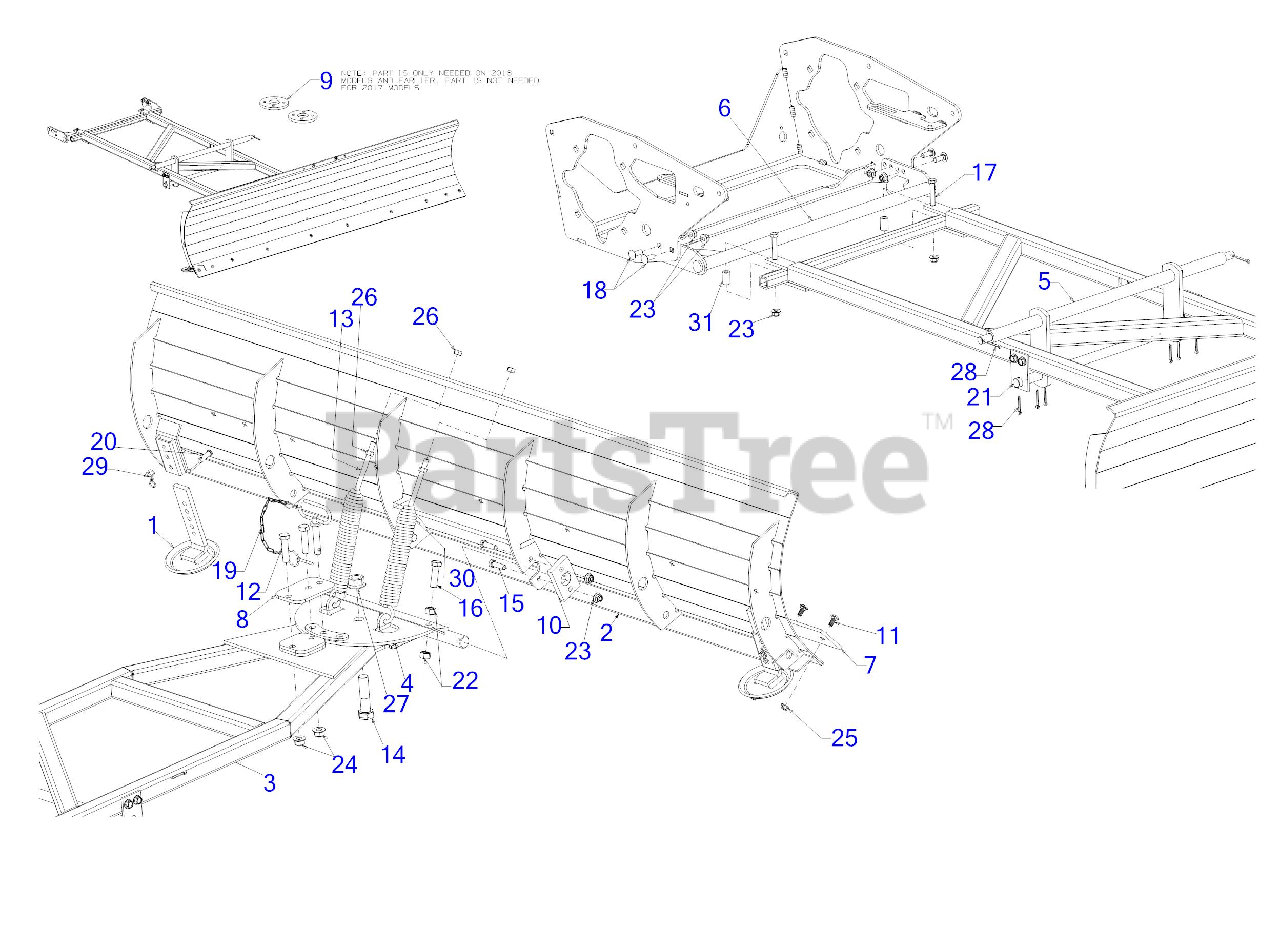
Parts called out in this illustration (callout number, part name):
2	72" SNOW BLADE WELDMENT
3	SNOW BLADE FRAME
4	BLADE PIVOT BRACKET
5	LIFT ROD WELDMENT
7	72" SCRAPER BLADE
10	PIVOT ROD PLATE
11	CARRIAGE BOLT 5/16-18 x .75
12	SCREW 1/2-13 x 2 GR5
13	SCREW 3/8-16 x 4.50
14	SCREW 3/4-16 x 3.0
15	SCREW 3/8-16 x 1.25 GR5
16	BOLT 1/2-13X1.75 GR5
17	SCREW 3/8-16 x 2.0 GR 8
18	CARRIAGE BOLT 3/8-16 x 1.00 GR5
20	CLEVIS PIN
21	SNOW BLADE LIFT BAR
22	HEX NUT
25	FLANGE NUT
26	HEX NUT
27	HEX FLANGE NUT 3/4
28	COTTER PIN-5/32 DIA
29	PIN:COTTER
30	ADJUSTMENT SPRING
31	SPACER:.385 ID x .63
